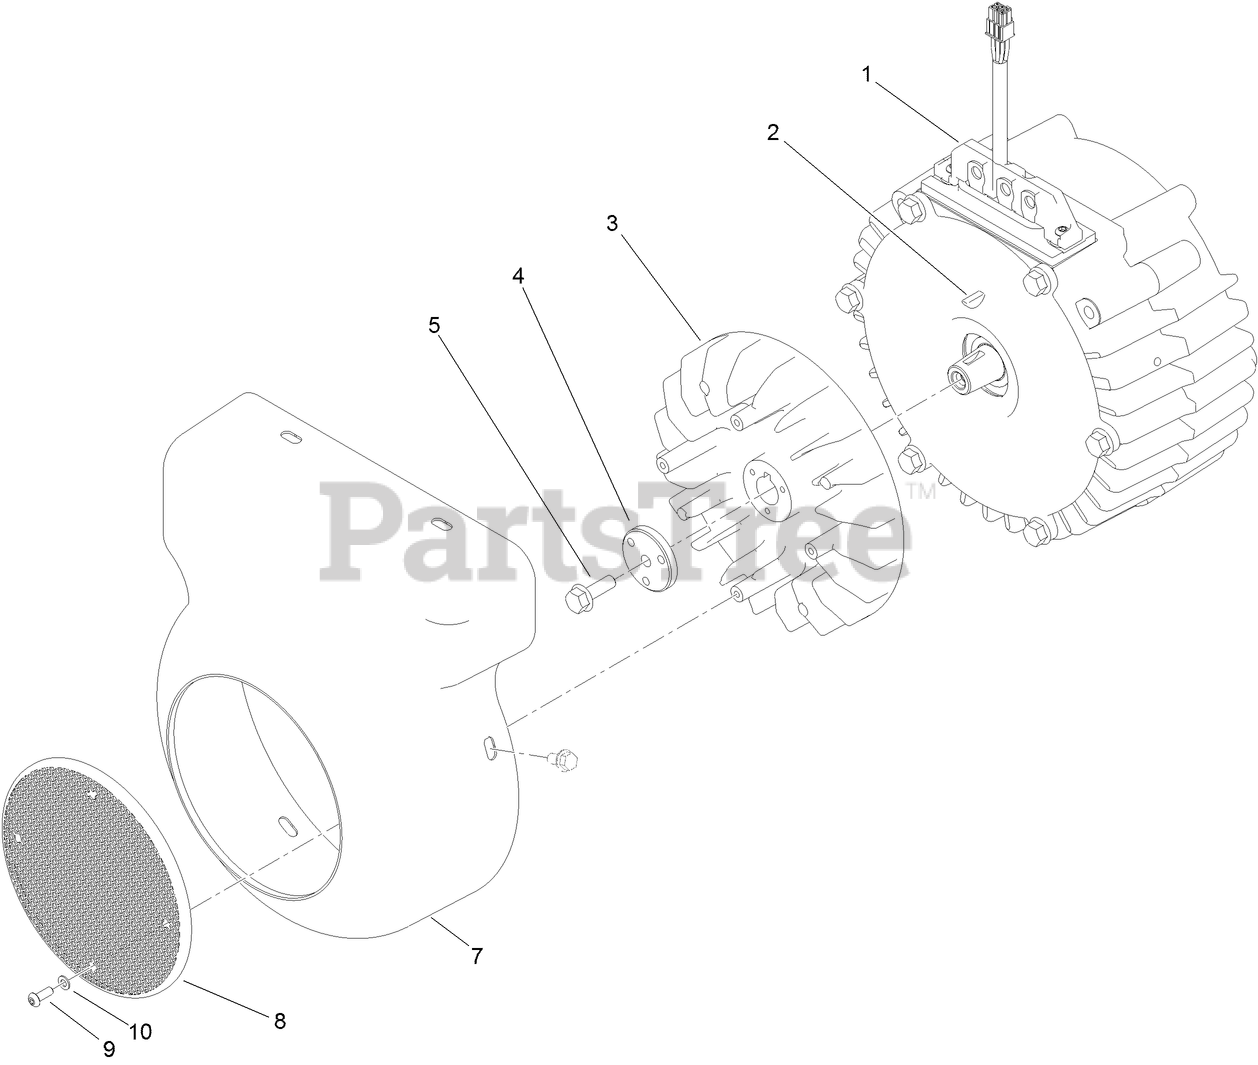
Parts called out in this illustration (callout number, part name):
1	Generator Service ASM
2	Key-Woodruff
3	Fan-Generator
5	SCREW-HHF
7	Cover-Generator
8	Screen-Fan
9	Screw-BHCS
10	Washer-Flat
